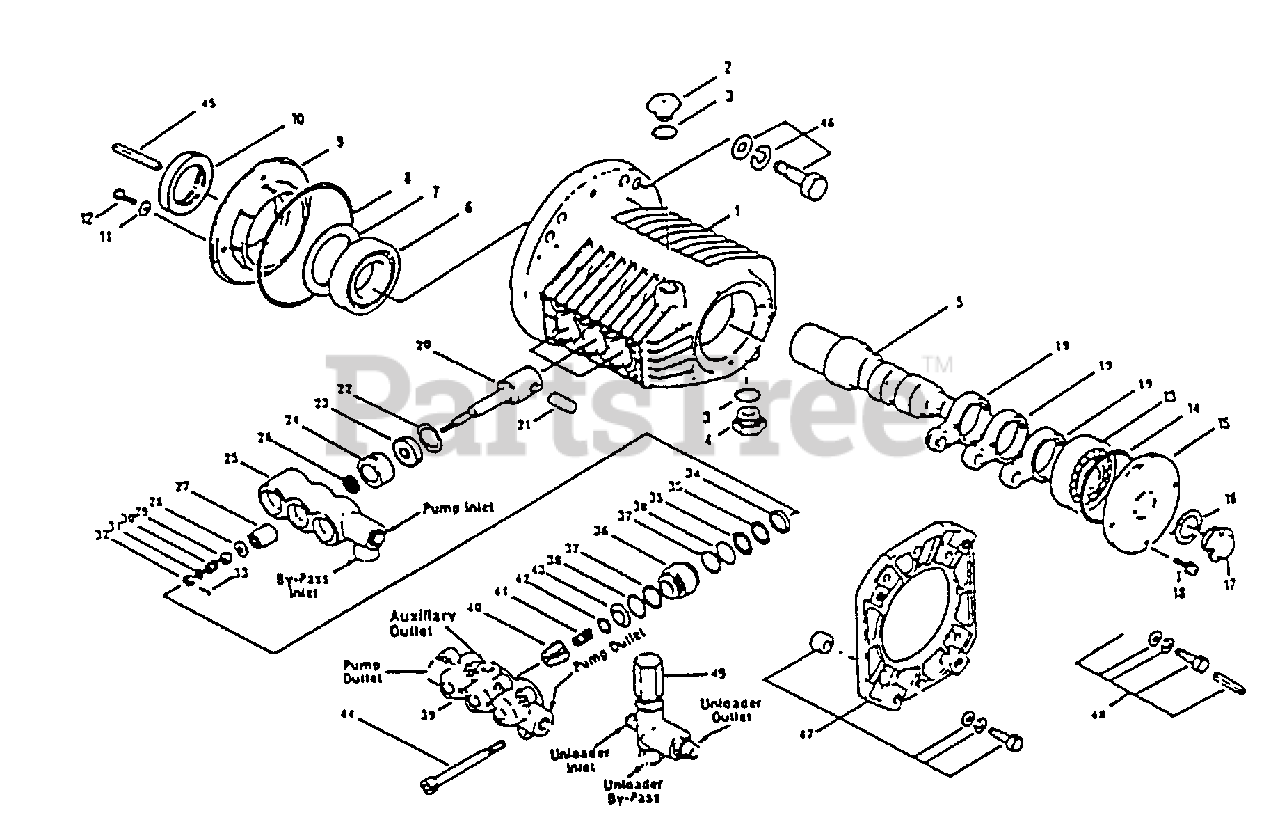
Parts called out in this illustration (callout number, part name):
1	Crankcase
2	Oil Filter Cap
3	O-Ring, Oil Filter Cap
4	Drain Plug
5	Crankshaft (5.0mm)
6	Bearing-Inner
7	Washer
8	O-Ring, Bearing Case
9	Bearing Case-Inner
10	Oil Seal
11	Sealing Washer
12	Sems. Comb. Head Screw (M6 x 20)
13	Bearing-Outer
14	O-Ring, Oil Gauge
15	Bearing Cover
16	Flat Flex Gasket
17	Bubble Oil Gauge
18	Sems. Comb. Head Screw (M6 x 16)
19	Connecting Rod-"H"
20	Piston Rod
21	Piston Pin
22	Seal Washer
23	Oil Seal
24	Seal Retainer
25	Inlet Manifold
26	Lo-Pressure Seal
27	Ceramic Plunger
28	Inlet Valve
29	Spacer
30	Inlet Valve Spring
31	Conical Washer (M6)
32	Slotted Nut (M6)
33	Cotter Pin
34	Female Adapter
35	V-Packing
36	Male Adapter-Spacer
37	Backup Ring
38	O-Ring, Adapter
39	Discharge Manifold-Bypass
40	Valve Spring Retainer
41	Valve Spring
42	Discharge Valve
43	Discharge Valve Seal
44	Hex, Socket Head Screw (M8 x 100)
46	Bolt Mount Kit-Gas
46	Bolt Mount Kit - Electric
47	Adapter Mount Kit - Gas
48	BS Bolt Kit (Short Shaft Eng.)
49	Regulating Unloader
